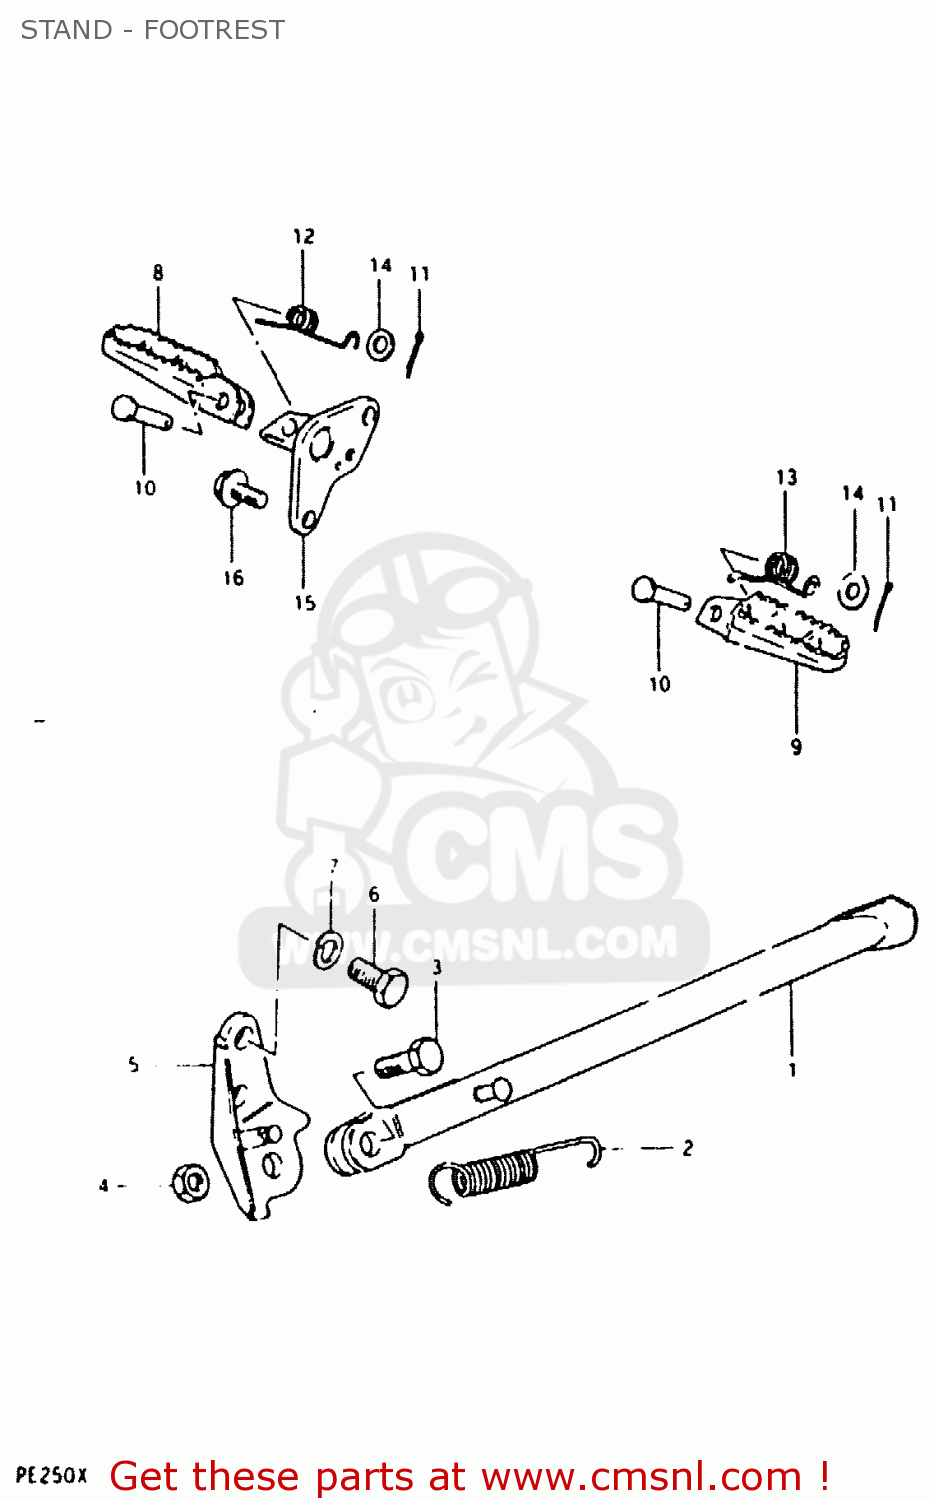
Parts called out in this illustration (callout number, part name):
1	STAND,SIDE
2	SPRING
3	BOLT(10X30)
4	NUT
5	BRACKET,PROP STAND
6	BOLT(10X19)
7	LOCK WASHER
8	RUBBER,FRONT FOOTREST
9	FOOTREST
10	PIN
11	PIN 20X20
12	SPRING
13	SPRING
14	WASHER
15	HOLDER,FRONT FOOTREST,RIGHT
16	BOLT(10X20)
